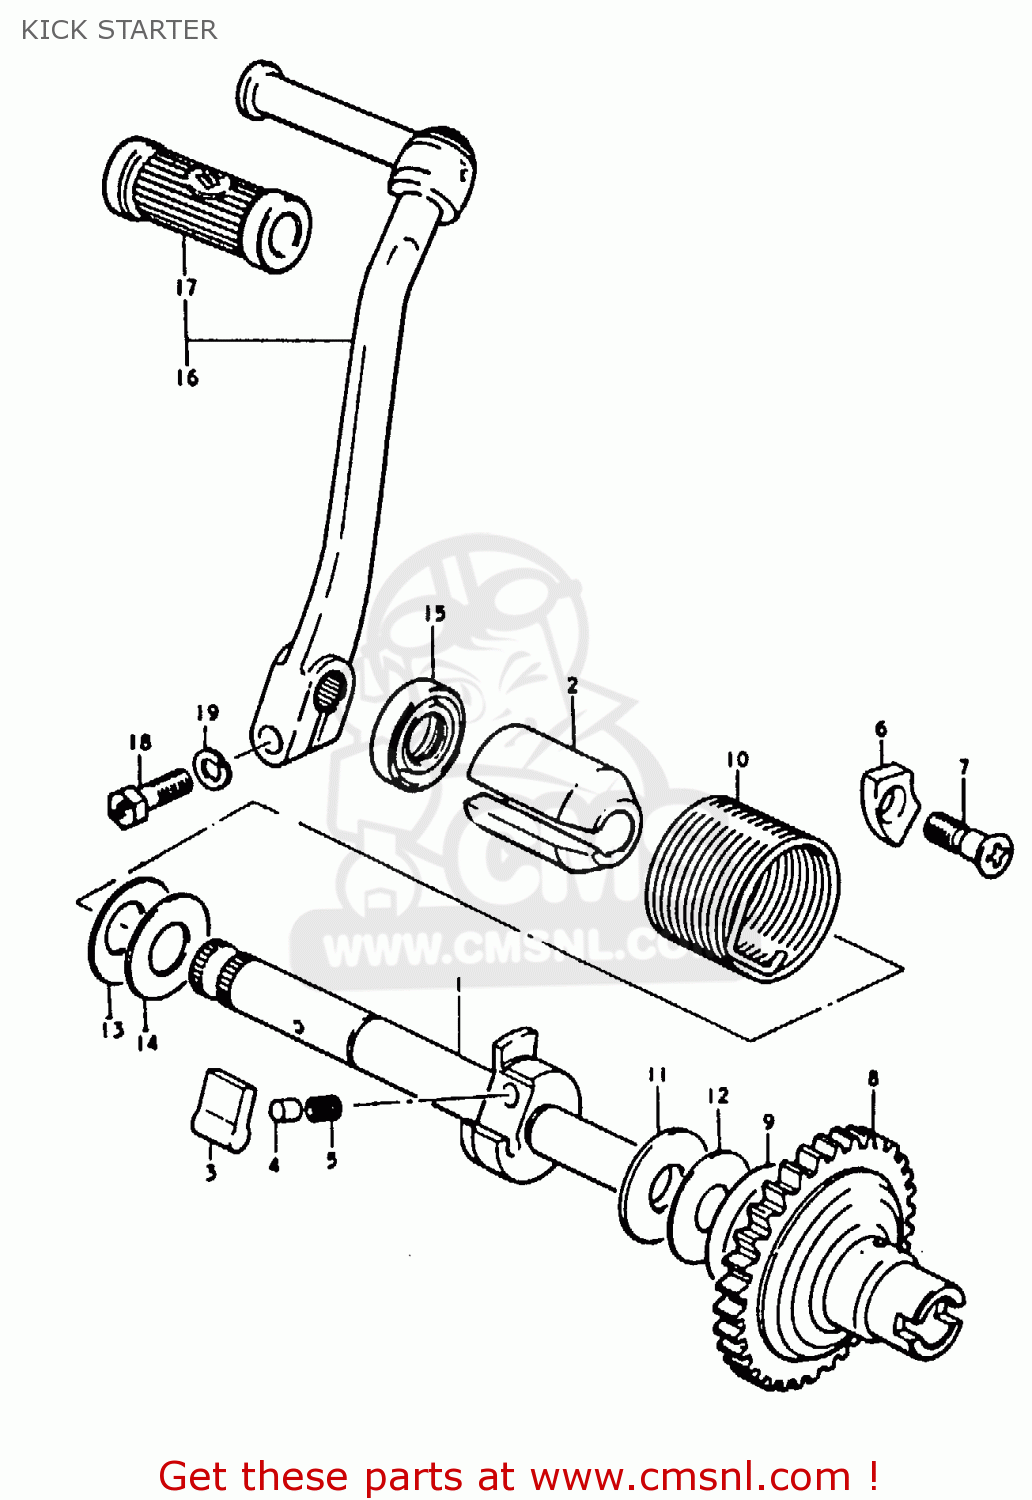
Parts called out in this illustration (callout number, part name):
1	SHAFT,KICK STARTER
2	GUIDE,KICK STARTER SFT SPRING
3	PAWL,KICK STARTER
4	PIN(5X15.5)
5	SPRING
6	LIFTER,KICK STARTER PAWL
7	SCREW
8	GEAR, KICK STARTER DRIVE
9	OIL SEAL
10	SPRING
11	SHIM(12X30X0.5)
14	WASHER(16X30X1)
15	SEAL,OIL(16X30X8)
16	LEVER ASSEMBLY,KICK STARTER
17	RUBBER,KICK STARTER PEDAL
18	BOLT
19	LOCK WASHER
